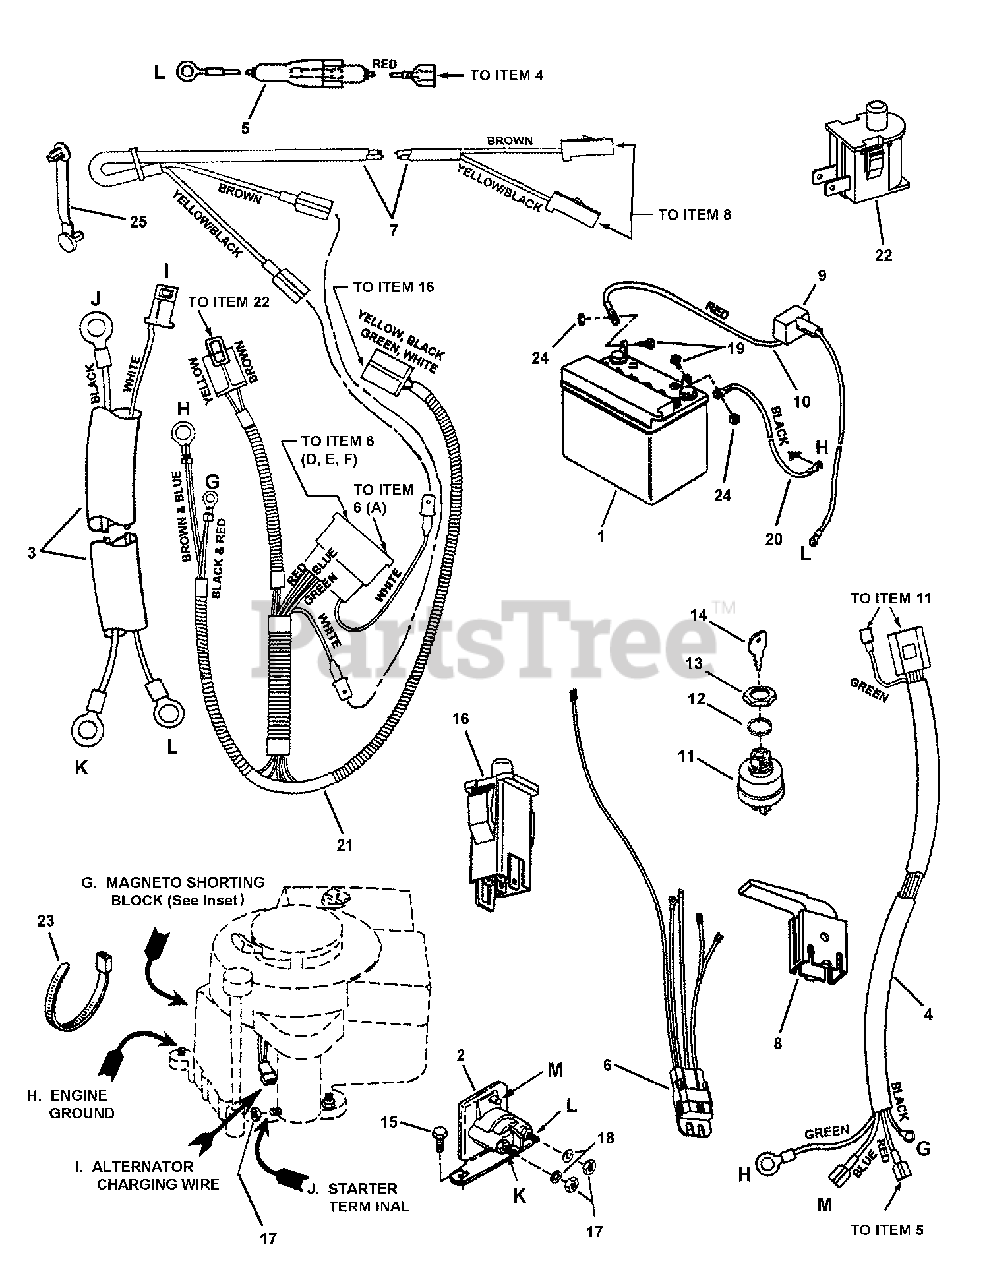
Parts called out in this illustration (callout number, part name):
1	KIT, Battery, 12V, U-1-7RS, 220CCA Dry Charge Snapper No Spill
2	SOLENOID, Super-Trombetta
3	HARNESS, Starter Wiring (Briggs Engines)
4	HARNESS, Ignition Wiring (Briggs Engines)
5	HOLDER, Fuse (Includes Fuse)
6	INTERLOCK MODULE, Briggs
7	HARNESS, (Deck Interlock Wiring)
8	SWITCH, Deck Interlock (NO)
9	COVER, Battery Cable
10	WIRE, Positive (Red, 17" long)
11	SWITCH, Ignition, 4 Terminal, Indak
12	WASHER, 5/8" Internal Tooth Lock
13	NUT, 5/8-32 Hex
14	KEYS, Blister Pk (KIDS+MWRS DON'T MIX) English/Spanish (set of two, one coated)
15	SCREW, 1/4-20 x 1/2" Hex Washer Self-Tap
16	SWITCH, Operator Presence Control (OPC) Traction (NC/NO)
17	NUT, 1/4-20 Hex, GR 5 or B
18	WASHER,1/4" Internal Tooth Lock
19	SCREW, 1/4-20 x 5/8" Hex Head Cap GR 5
20	WIRE, Negative, Black (15" long)
21	HARNESS, Operator Presence Control (OPC) Wire
22	SWITCH, Seat (NC)
23	CABLE TIE, 7"
24	NUT, 1/4-20 Hex Center Lock, GR 5 or B
25	CABLE TIE, 7"
